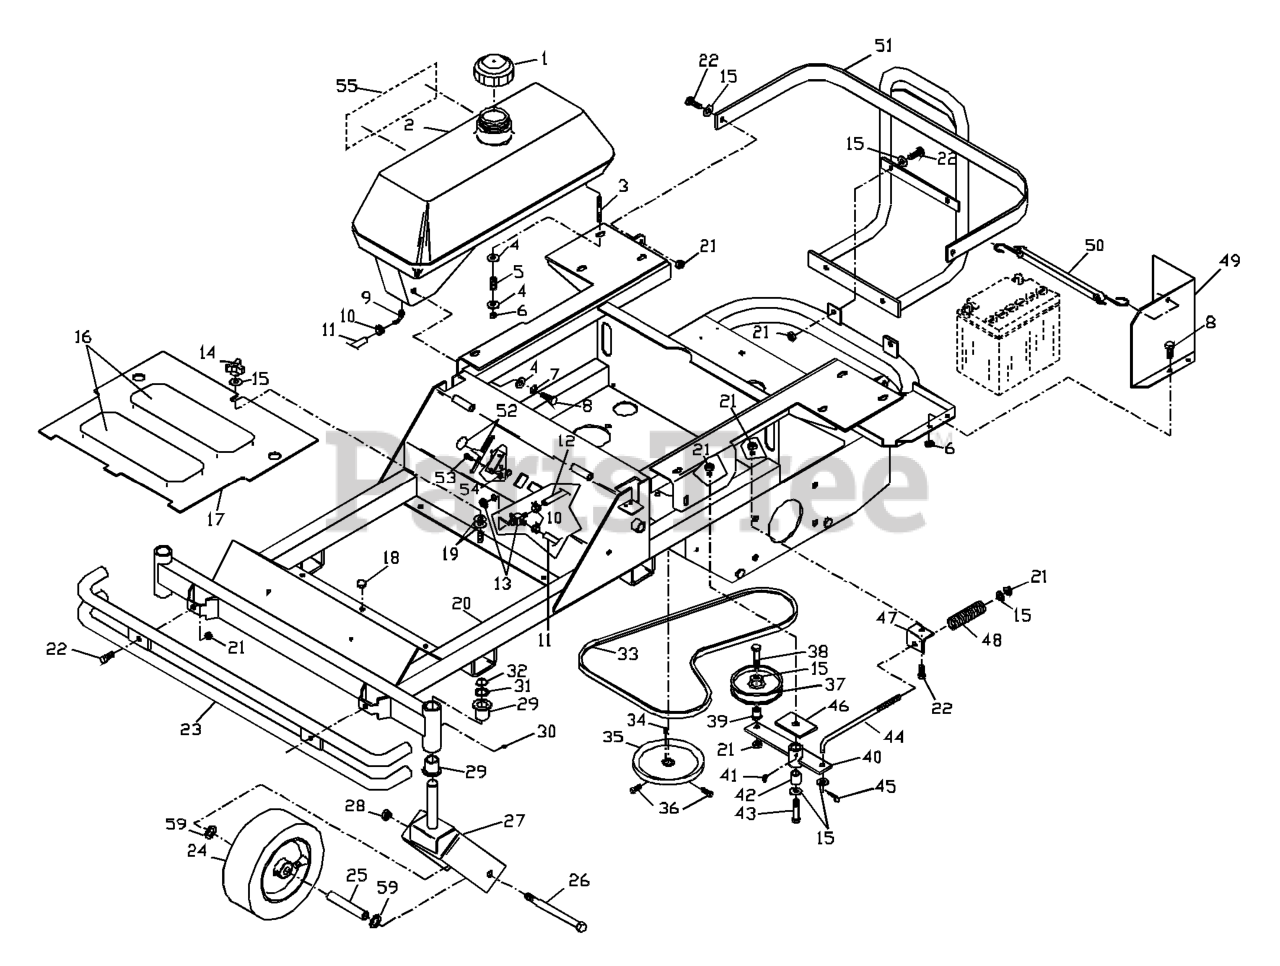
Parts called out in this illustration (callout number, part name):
1	FUEL CAP
2	FUEL TANK RT
3	STUD, 5/16C
4	WASHER 5/16 FLAT
6	NUT 5/16C CENTERLOCK
7	WASHER.LOCK.HVY.HLCL.SPR.5/16
8	HCS 5/16C X 3/4
9	HOSE BARB 90 DEGREE
10	HOSE CLAMP
11	FUEL LINE 21.5" TANK
12	FUEL LINE, ENGINE
13	FUEL VALVE
14	KNOB, THREE PRONG
15	WASHER 3/8 FLAT
16	ANTI-SKID PAD
17	FOOTPLATE
18	GROMMET, BUMPER
19	WASHER, 3/8 DISC SPRING SPEC
20	FRAME W/DECALS KOHLER
20	FRAME W/DECALS KAWASAKI
21	NUT 3/8C CENTERBLOCK
22	HCS 3/8-16X1.GRD.5.ZD
23	BUMPER, FRONT
24	TIRE, CASTER (COMPLETE)
24	TIRE.11X4.00-5NHS.4PR.SMOOTH
24	ROLLER BEARING-CAGED 3 1/4'
24	ZERK
24	BEARING RETAINER
26	HCS 1/2C X 5 1/2
27	YOKE WELDMENT ORANGE
28	NUT 1/2-13 HEX NYLOC ZD
29	BUSHING, FLANGED
30	ZERK
31	BSHG .875 X 1.375 X .074 ZD
32	RETAINING RING, 7/8"
34	KEY 5 MM SQ X 25 MM
36	SCREW 5/16C X 5/8 SQ HEAD
37	IDLER PULLEY
38	HCS 3/8-16 X 1 3/4 GR5
39	BUSHING, IDLER FLANGE
40	IDLER ARM WELDMENT
41	ZERK
42	PIVOT BUSHING
43	HCS 3/8C X 3
44	TENSION ROD
45	RP_COTTER PIN 1/8 X 3/4
46	SUPPORT PLATE
47	TENSION BRACKET
48	COMPRESSION SPRING
49	BATTERY GUARD W/DECA
50	BATTERY STRAP
51	ENGINE GUARD W/DECAL
52	THROTTLE CABLE
53	HCS #10-24 X 1/2
54	NUT 10-24 NYLOC
55	DECAL, ZTH4218
55	DECAL ZTH4221
55	DECAL, ZTH4818
55	DECAL ZTH4820
55	DECAL, ZTH4821
56	HCS 3/8C X 2 1/4
57	WEIGHT BLOCK
58	CHOKE CONTROL, COMPLETE
